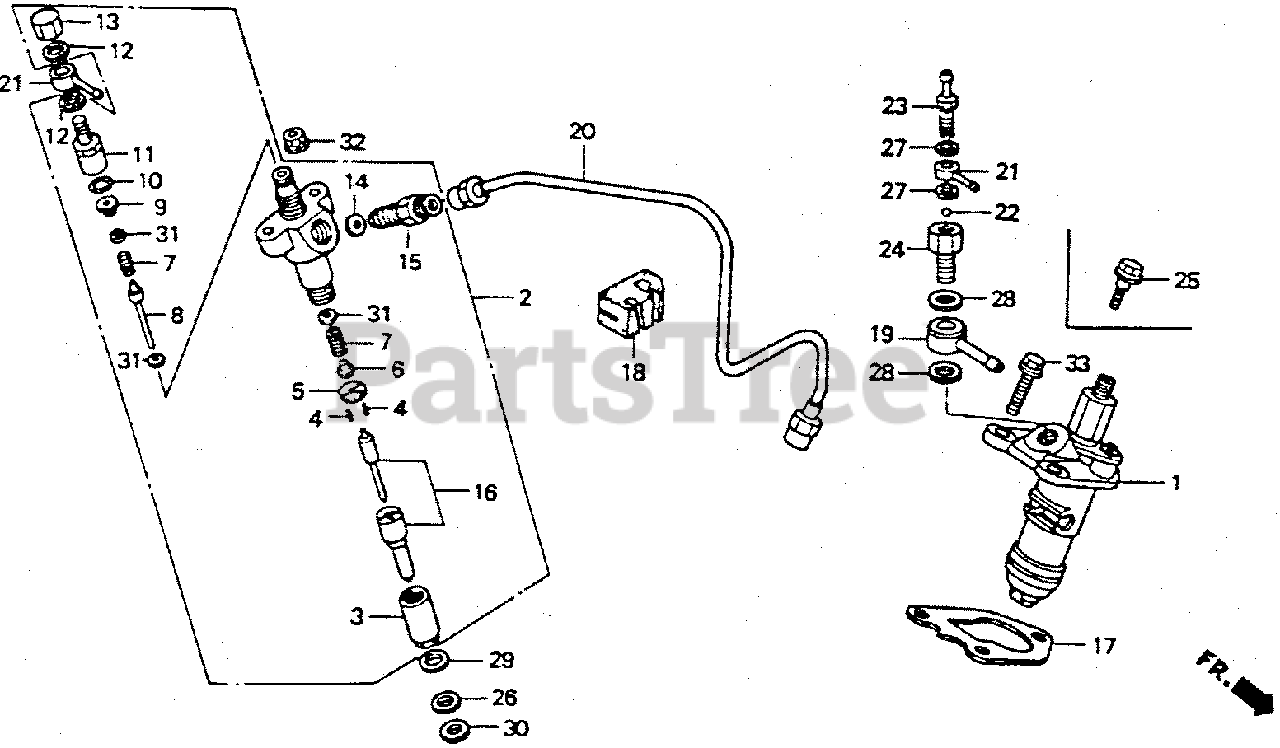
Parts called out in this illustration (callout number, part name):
1	PUMP ASSY., FUEL INJECTION
2	NOZZLE & HOLDER ASSY.
3	NUT, RETAINING
4	PIN (1.78X9.3)
5	SPACER
6	SEAT, SPRING (A)
7	SPRING, NOZZLE
8	ROD, PUSH
9	SEAT, SPRING (B)
10	O-RING
11	NUT, CAP
12	GASKET A
13	NUT
14	GASKET B
15	CONNECTOR, IN.
16	NOZZLE
17	GASKET, FUEL INJECTION PUMP (0.2) (C)
17	GASKET, FUEL INJECTION PUMP (0.3) (D)
17	GASKET, FUEL INJECTION PUMP (0.4) (E)
17	GASKET, FUEL INJECTION PUMP (0.1) (A)
17	GASKET, FUEL INJECTION PUMP (0.15) (B)
17	GASKET, FUEL INJECTION PUMP (0.5) (F)
17	GASKET, FUEL INJECTION PUMP (0.6) (G)
18	RUBBER, FUEL TUBE CLAMP
19	JOINT, FUEL
20	PIPE, FUEL
21	JOINT, AIR BREATHER (B)
22	BALL, CHECK
23	BOLT, AIR BREATHER (8X20)
24	BOLT, FUEL JOINT (12X25.5)
25	BOLT, ROTARY TRANSMISSION
26	WASHER, PLAIN (7MM)
27	WASHER (8MM)
28	WASHER, FUEL JOINT
29	GASKET A, NOZZLE (0.8)
29	GASKET B, NOZZLE (1.0)
29	GASKET, NOZZLE
29	GASKET D, NOZZLE (1.4)
30	GASKET, SPECIAL (7MM)
31	SHIM A (0.50)
31	SHIM B (0.51)
31	SHIM C (0.52)
31	SHIM D (0.53)
31	SHIM E (0.54)
31	SHIM F (0.55)
31	SHIM G (0.56)
31	SHIM H (0.57)
31	SHIM I (0.58)
31	SHIM J (0.59)
31	SHIM K (0.60)
31	SHIM L (0.70)
31	SHIM M (0.80)
31	SHIM N (0.90)
32	NUT, FLANGE (6MM)
33	BOLT, FLANGE (8X25)
